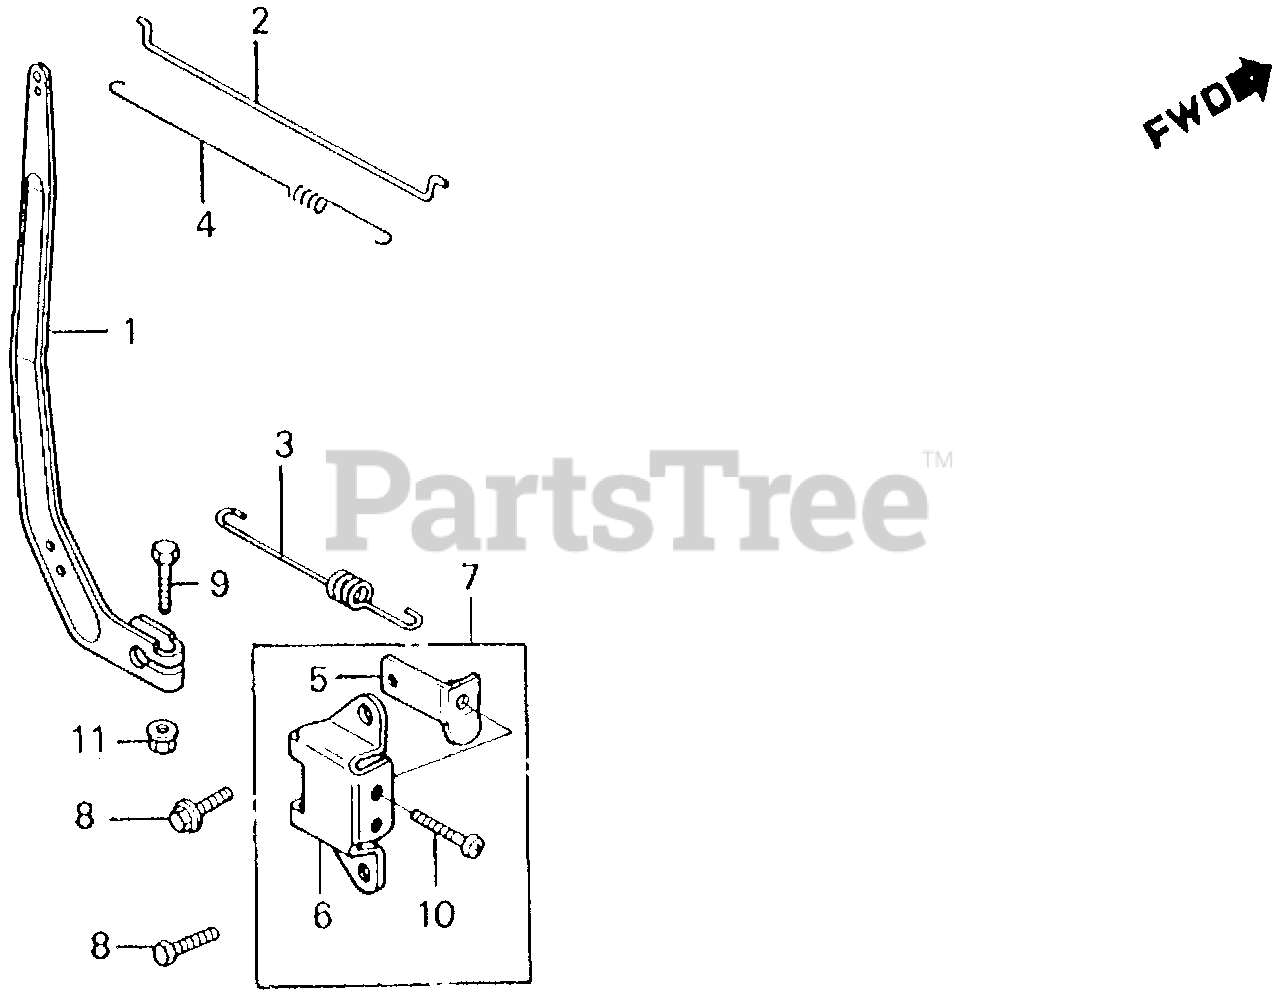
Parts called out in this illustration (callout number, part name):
1	ARM, GOVERNOR
2	ROD, GOVERNOR
3	SPRING, GOVERNOR
4	SPRING, THROTTLE RETURN
5	PLATE, CONTROL
6	BASE, CONTROL
7	LEVER, CONTROL
8	BOLT, FLANGE (6X12) (CT200)
9	BOLT, HEX. (6X20)
10	SCREW, PAN (6X28)
11	NUT, FLANGE (6MM)
